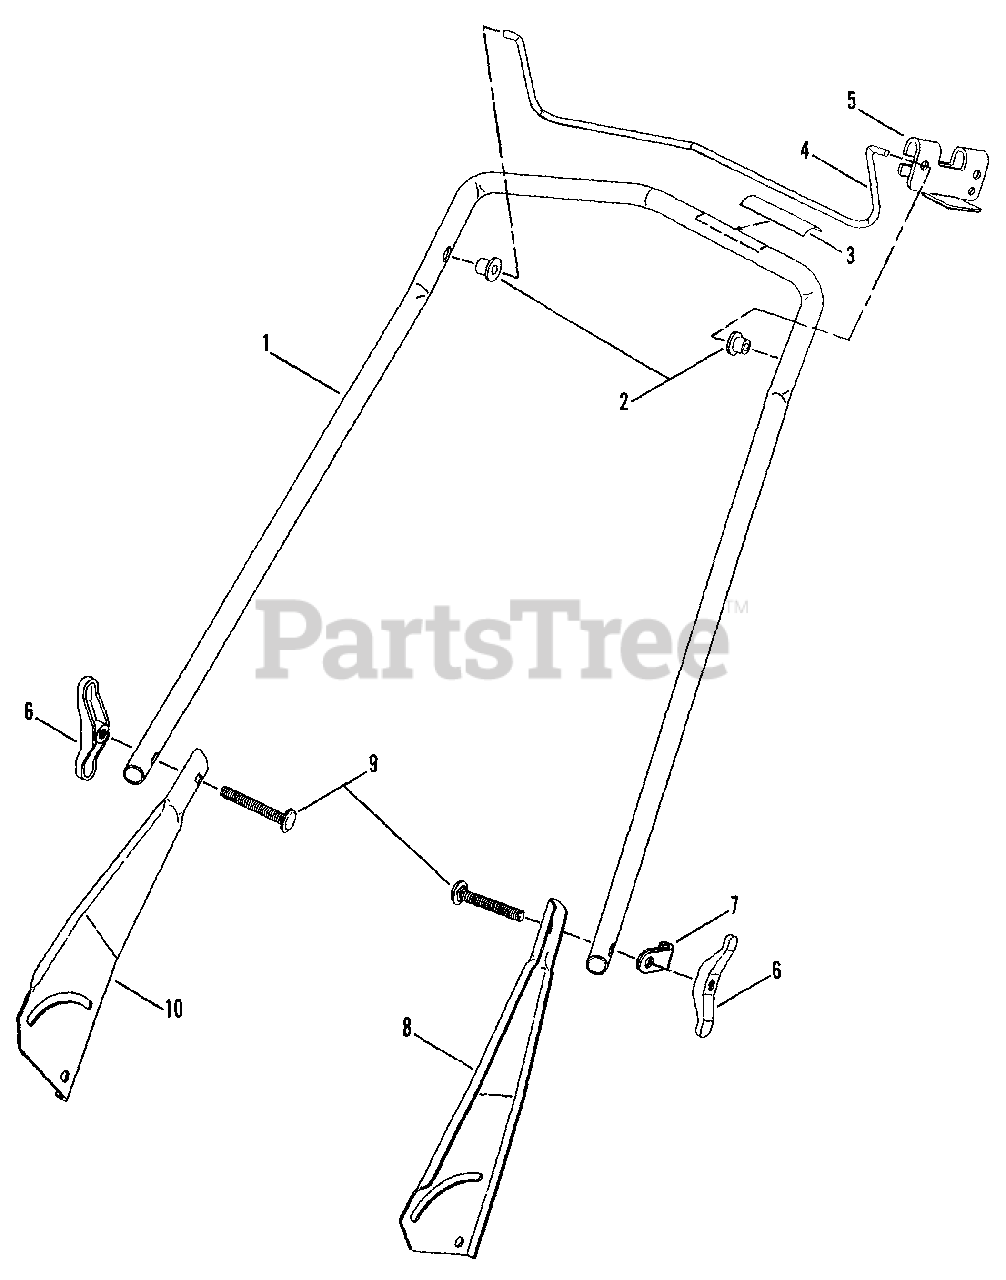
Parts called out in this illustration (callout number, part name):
1	HANDLE, Upper
2	BUSHING, Auger Control
3	DECAL, Auger Control Instruction
4	CONTROL, Auger
5	CLIP, Auger Control
6	WING-NUT, 1/4-20
7	CLAMP, Cable
8	BRACKET, Lower Handle (Left Side)
9	BOLT, 1/4-20 x 2" Square Neck Carriage, Grade 5
10	BRACKET, Lower Handle (Right Side)
